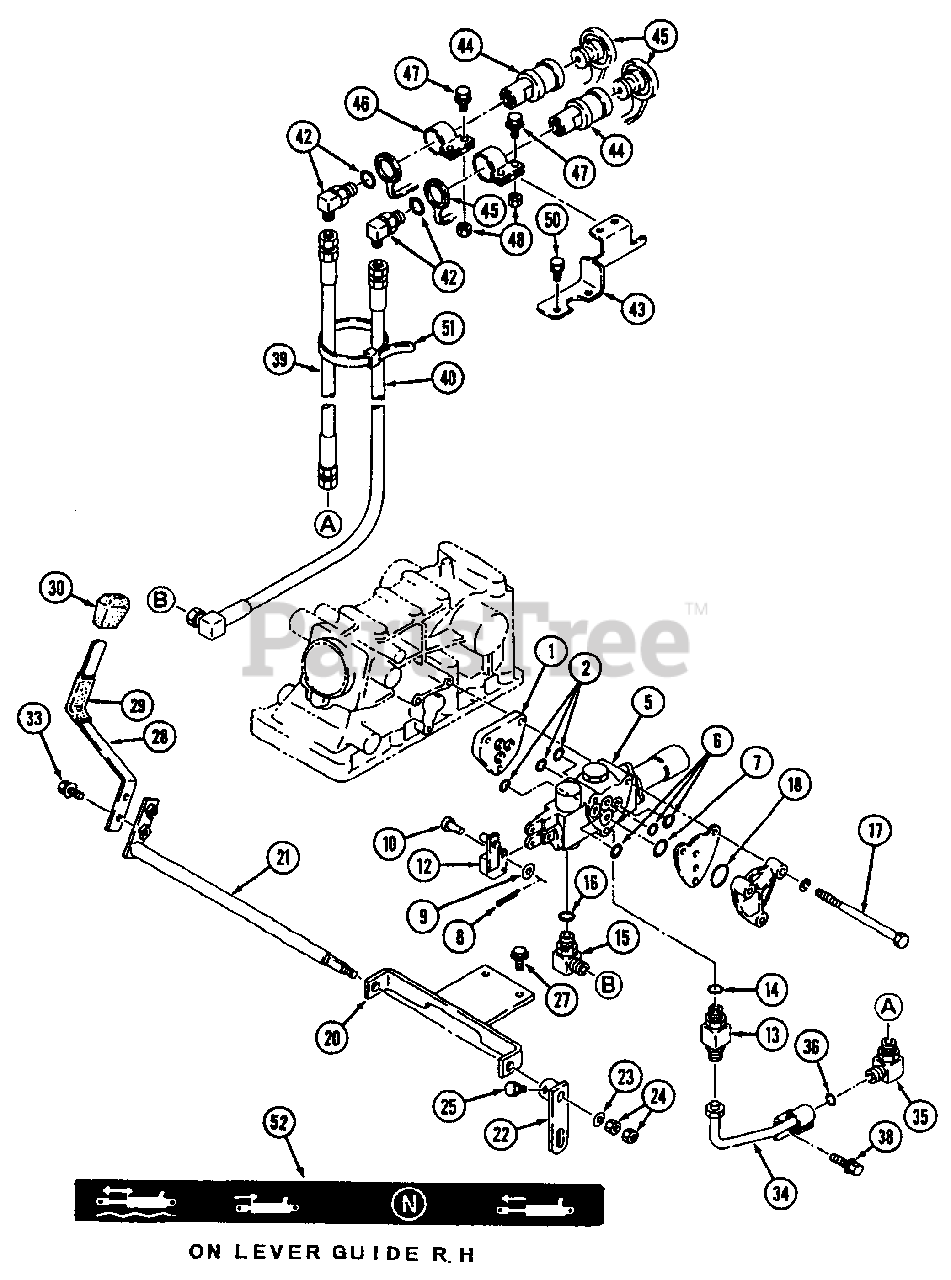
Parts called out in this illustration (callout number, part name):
5	Body
6	O-Ring
13	Body (Nipple)
15	Elbow 90
28	Lever
34	Pipe Press. Ass'y.
35	Elbow 90
44	Coupling
46	Clamp, Coupler
52	Label, Aux. Valve
